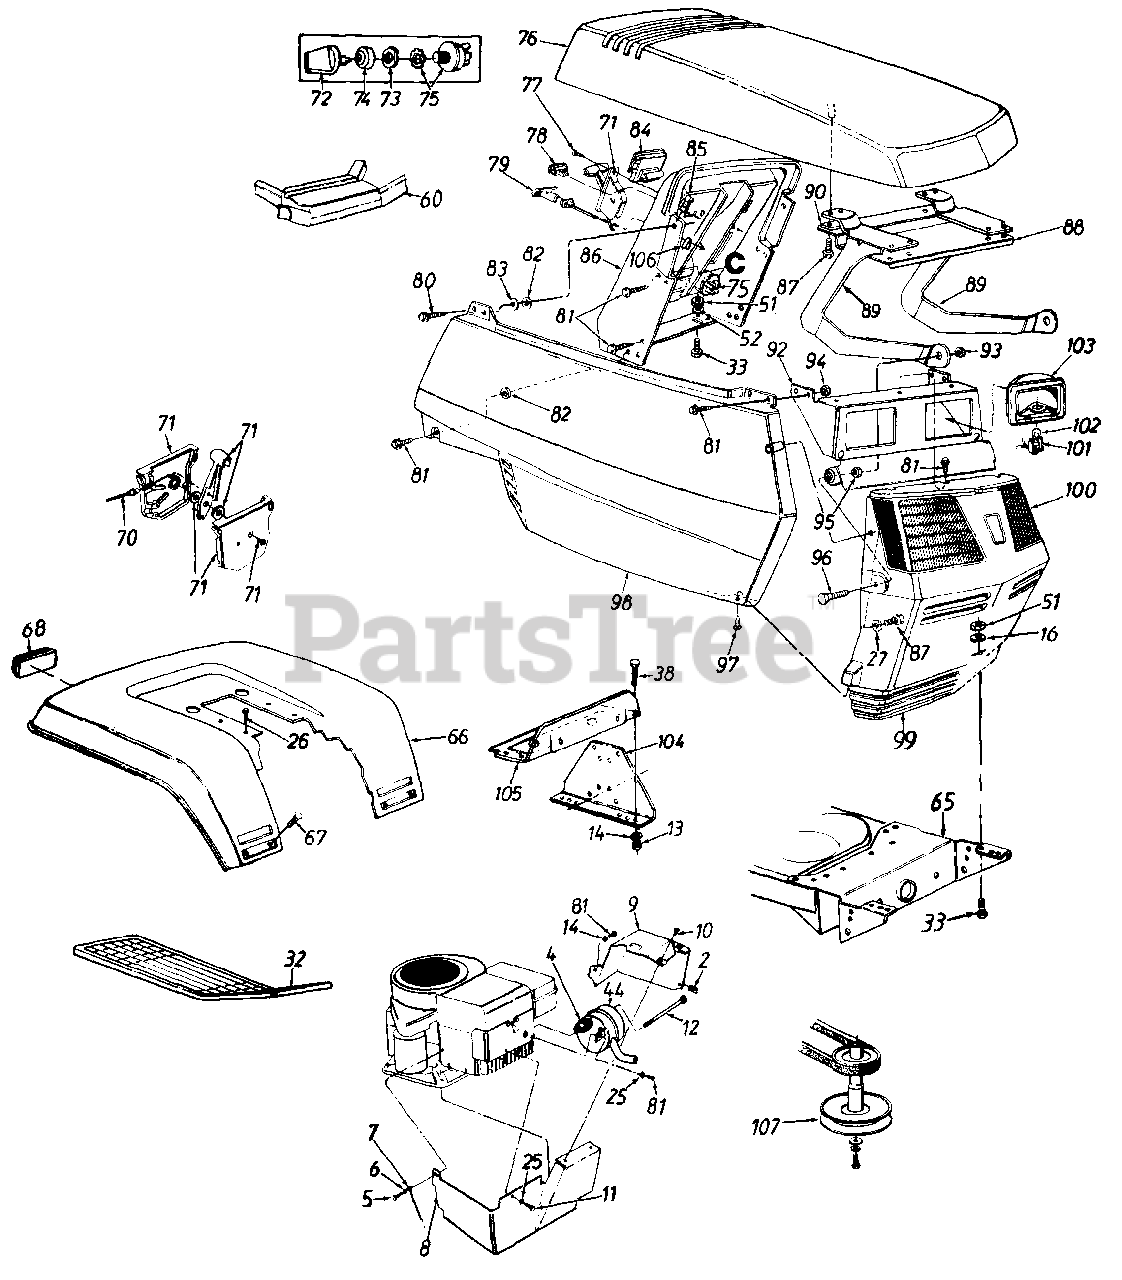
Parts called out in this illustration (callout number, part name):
2	Speed Nut #10-24 Thd.
4	Gasket
5	Truss Mach. Scr. 5/16-18 x .75"
6	External L-Wsh. 5/16" I.D.
7	Ground Wire
8	Muffler Heat Shield - Front
11	Hex Bolt 1/4-20 x 3/8" Lg.
12	Shld. Bolt 7/16" Dia. x 3-5/8" Lg.
13	Hex Nut 1/4-20 Thd.
14	L-Wash. 1/4" I.D.
16	Fl-Wash. .344" I.D. x 1" O.D.
25	Spr. Wash. .265" I.D.
26	Hex Wash. Hd. AB-Tap Scr. 5/16 x .75" Lg.
27	Fl-Wash. .218" I.D. x .5" O.D.
32	Rubber Foot Pad - L.H.
33	Hex Bolt 5/16-18 x .75" Lg.
38	Hex Bolt 1/4-20 x .62" Lg.
44	Muffler
51	Hex Nut 5/16-18 Thd.
52	Fl-Wash. .343" I.D. x .687"
60	Steering Wheel Insert
68	Reflector
70	Throttle Wire 18.5" Lg.
71	Throttle Control Box Ass'y.
72	Ignition Key
73	Ignition Switch Nut
74	Ignition Switch Cap
75	Ignition Switch
76	Hood
77	Truss Mach. AB-Tap Scr. #10 x .5" Lg.
78	Light Switch
79	Choke Control
80	Hex Wash. Hd. Tap Scr. 1/4 x .75" Lg.
81	Hex Tap Scr. 1/4-20 x .5" Lg.
82	Push Nut Fastener
83	Fl-Wash. .27" I.D. x .948"
84	Ammeter
85	Speed Nut 1/4-20 Thd.
86	Dash Panel
87	Hex Wash. Hd. B-Tap Scr. 1/4 x .62" Lg.
94	Hex L-Nut 1/4-20 Thd.
95	Hex Jam Nut 5/16-18 Thd.
96	Hex Bolt 5/16-18 x 7/8" Lg.
97	Truss Mach. B-Tap Scr. #10 x .5" Lg.
98	Side Cover - R.H.
99	Grille
100	Lens - L.H.
101	Twist Lock - Lamp Socket
102	Lamp
103	Headlight Housing
107	Engine Pulley 30" Deck Only
